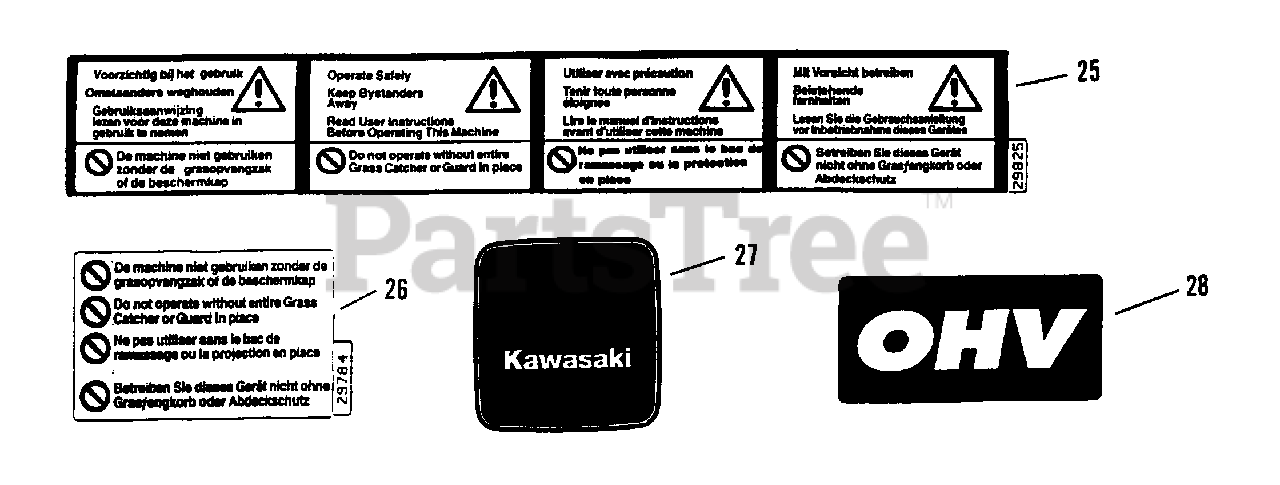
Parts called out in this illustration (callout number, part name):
25	DECAL, - WARNING
26	DECAL, Deck/Chute, International Warning
27	DECAL, Kawasaki Engine (Starter)
28	DECAL, Kawasaki Engine (OHV)
